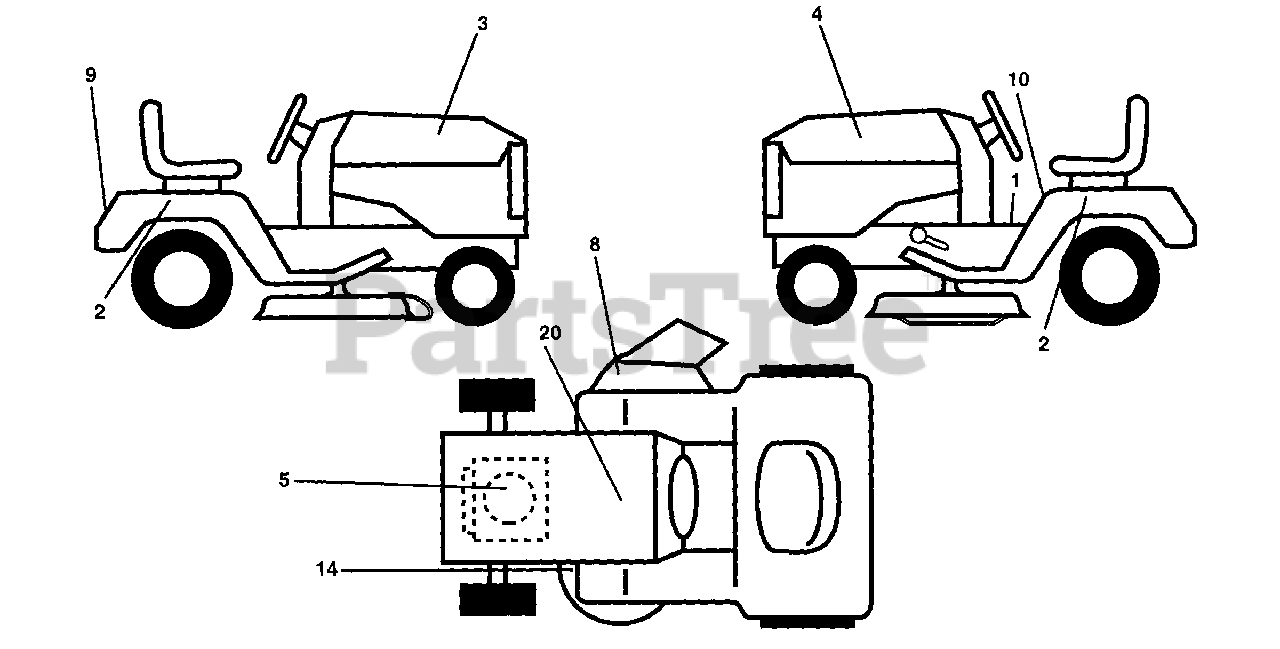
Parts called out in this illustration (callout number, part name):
1	Decal Oper Step Thru E/F
2	Decal Fender Auto Husq. Radius
3	Decal Hood LH
4	Decal Hood RH
8	Decal Warning
9	Decal Fender Husq
10	Decal Fender Danger E/F
14	Decal V-Belt Schematic
20	Decal Bat Dan/Psn
